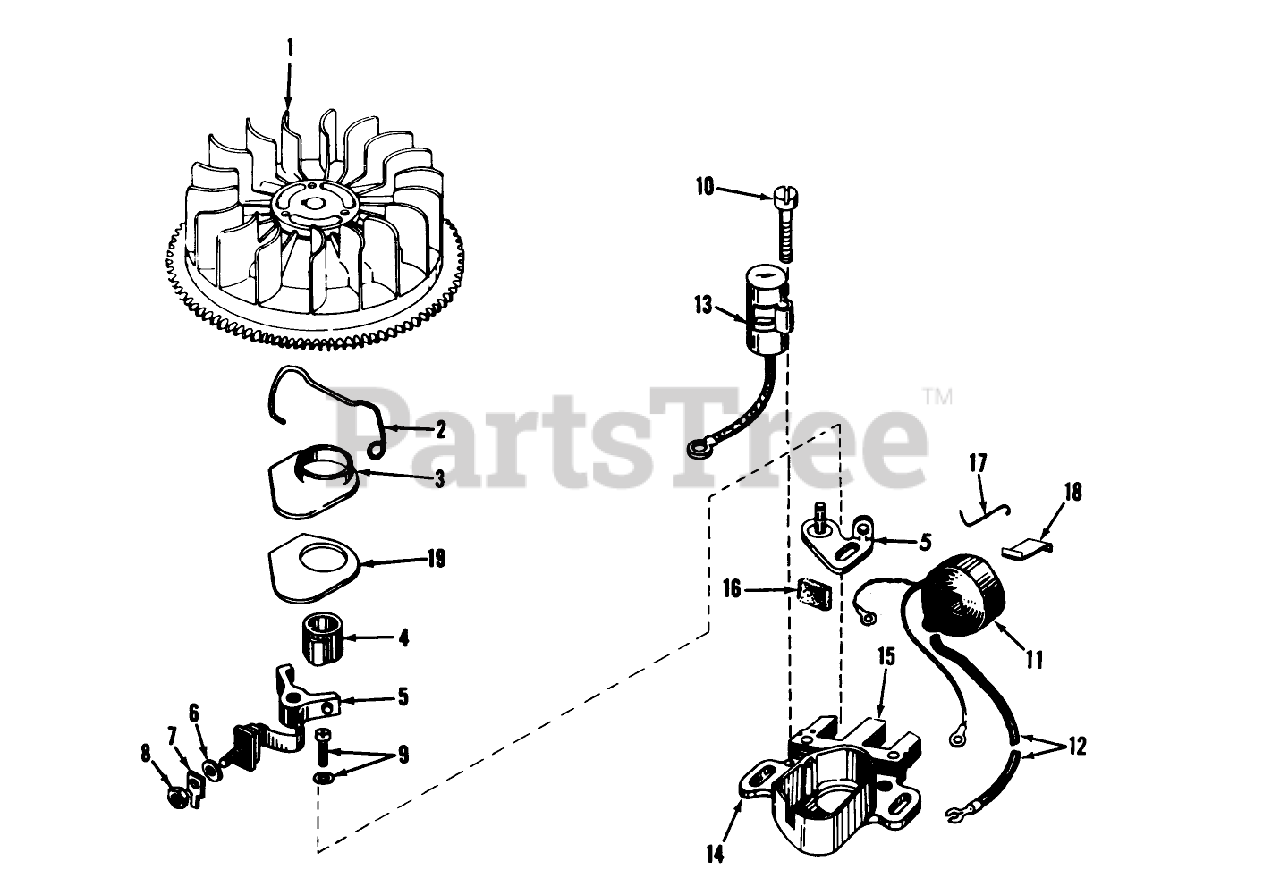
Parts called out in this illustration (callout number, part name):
1	Flywheel
2	Spring Breaker Box
3	Cover, Dust
4	Cam-Breaker
5	Breaker Assy.
6	Washer
7	Terminal
8	DECAL
9	Breaker Screw
10	Condenser Screw
11	Coil Assy. (Incl. No. 12)
12	Wire, Lead
13	Condenser
14	Core Plate
15	Stator Assy., (Incl. Nos. 2, 3, 5 thru 14 16 thru 19)
16	Felt,Cam Wiper
17	Clip, Coil
18	Spring Coil Wedge
19	Gasket, Dust Cover
